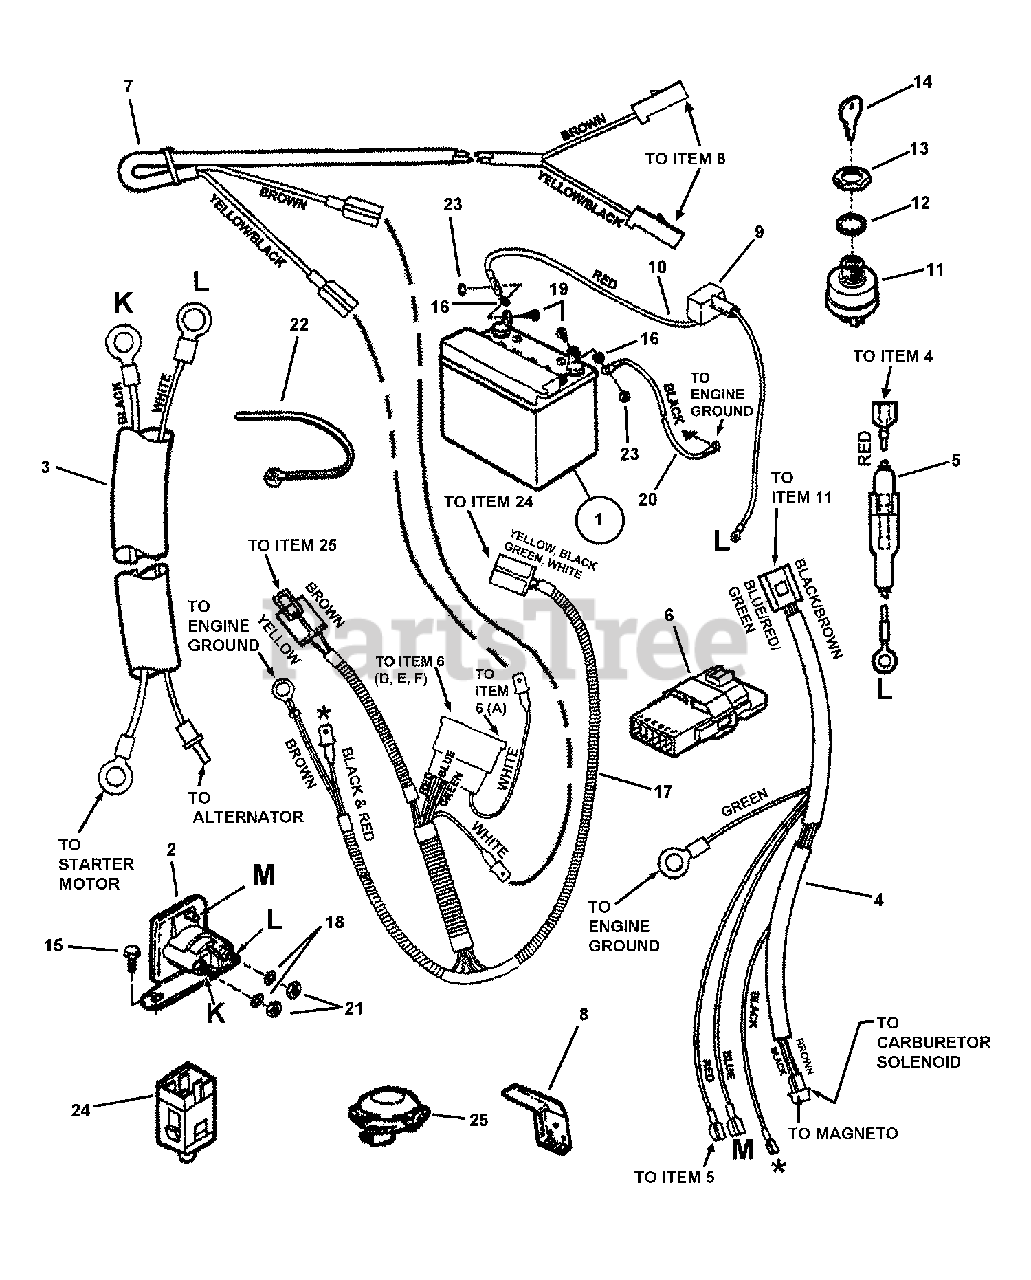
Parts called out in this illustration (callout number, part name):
1	KIT, Battery, 12V, U-1-7RS, 220CCA Dry Charge Snapper No Spill
2	SOLENOID, Super-Trombetta
3	HARNESS, Starter Wiring (Briggs)
4	HARNESS, Ignition Wiring (14.5 B&S)
5	HOLDER, Fuse (Includes Fuse)
6	INTERLOCK MODULE, Briggs
7	HARNESS (Deck Interlock Wiring)
8	SWITCH, Deck Interlock (NO)
9	COVER, Battery Cable
10	WIRE, Positive (Red, 17" long)
11	SWITCH, Ignition-Afterfire Solenoid
12	WASHER, 5/8" Internal Tooth Lock
13	NUT, 5/8-32 Hex
14	IGNITION KEY, Pair
15	SCREW, 1/4-20 x 1/2" Hex Washer Self-Tap
16	RETAINER, 1/4" Bolt
17	HARNESS WIRE, Operator Presence Control (OPC)
18	WASHER,1/4" Internal Tooth Lock
19	SCREW, 1/4-20 x 5/8" Hex Head Cap. GR5
20	WIRE, Negative, Black (15" long)
21	NUT, 1/4-20 Hex, GR5 or B (attaches to starter terminal)
22	CABLE TIE, 7"
23	NUT, 1/4-20 Hex Center Lock, GR5 or B
24	SWITCH, Operator Presence Control (OPC) Traction (NO/NC)
25	SWITCH, Seat (Normally Closed)
